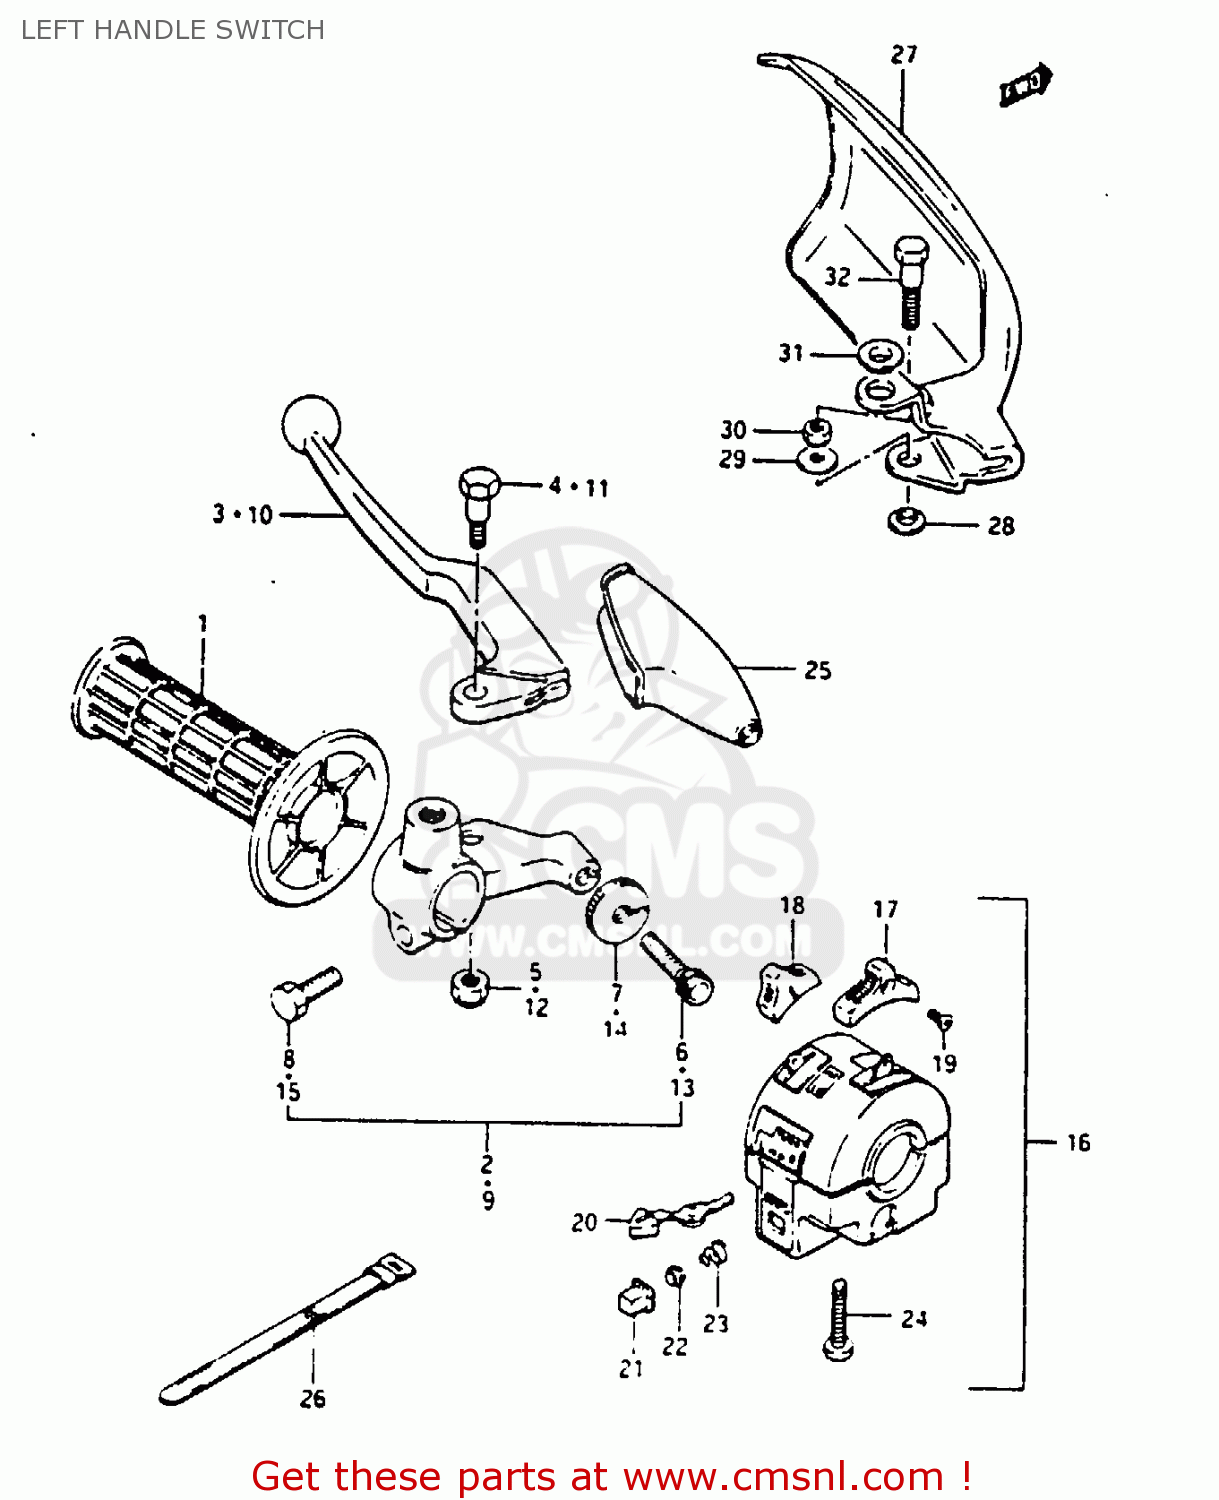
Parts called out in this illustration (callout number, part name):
1	GRIP, LH
2	LEVER ASSY, CLUTCH
3	LEVER,CLUTCH
4	BOLT,LEVER
5	NUT
6	ADJUSTER,CABLE
7	NUT,CABLE ADJUSTER LOCK
8	BOLT
9	LEVER ASSY,CLUTCH
10	LEVER,CLUTCH
11	BOLT,LEVER PIVOT
12	NUT
13	ADJUSTER,CABLE
14	NUT,CABLE ADJUSTER
15	BOLT,CLUTCH LEVER HOLDER
16	SWITCH ASSY,HANDLE LH
17	KNOB,LIGHTING SWITCH
18	KNOB,DIMMER SWITCH
19	SCREW
20	KNOB,TURNSIGNAL
21	BUTTON,HORN
22	CONTACT
23	SPRING
24	SCREW
25	COVER,CLUTCH LEVER
26	CLAMP(L:120)
27	COVER,KNUCKLE,L
28	WASHER
29	WASHER(6.5X16X1.2)
30	NUT 6MM
31	WASHER
32	BOLT,LEVER PIVOT
